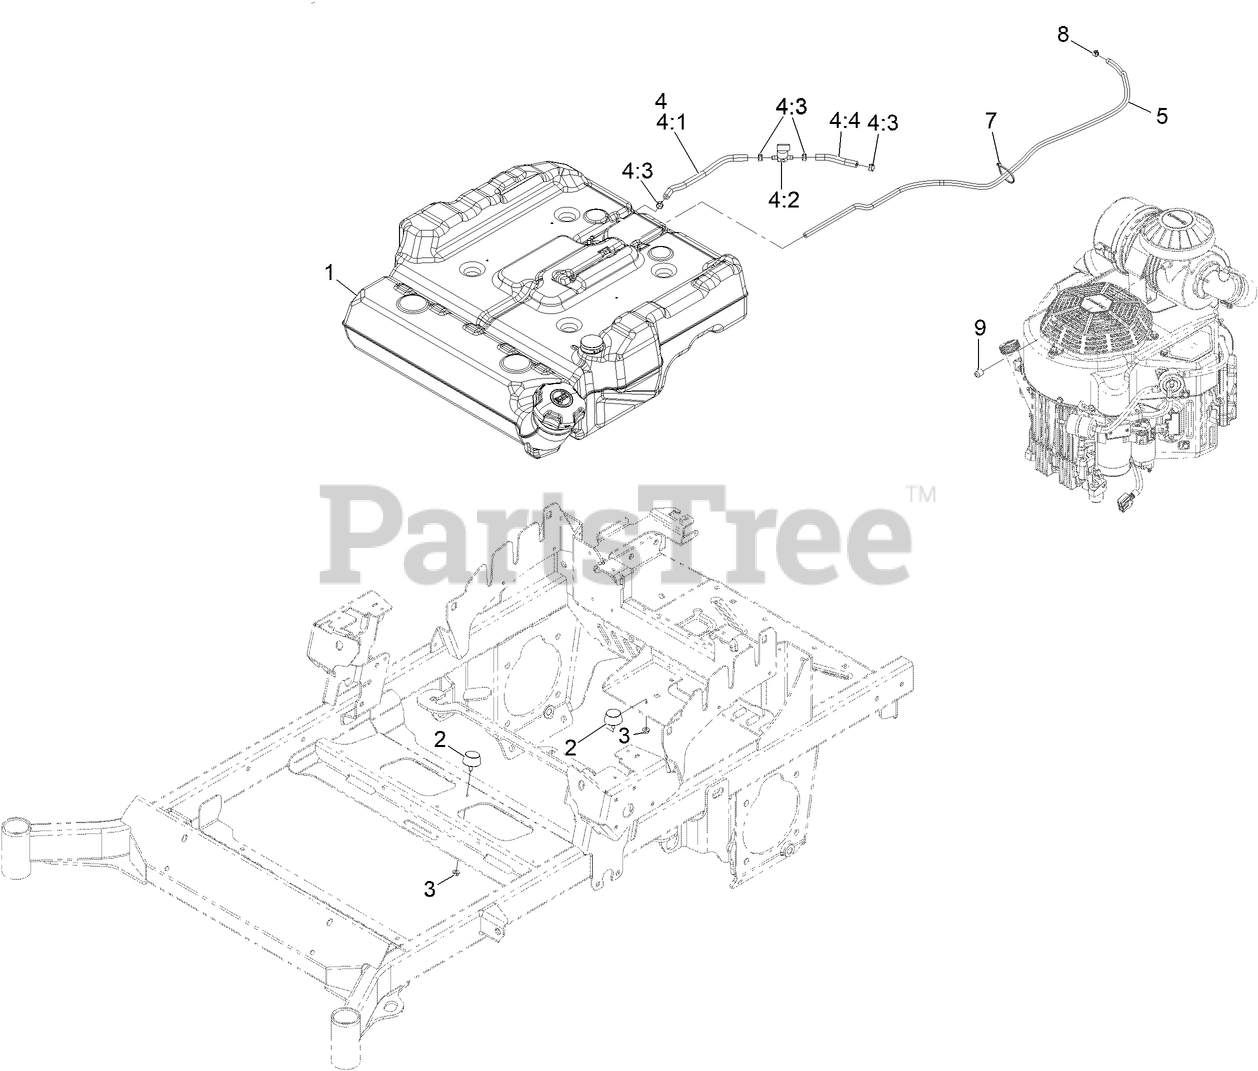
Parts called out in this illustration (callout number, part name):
1	ASM, Fuel Tank
4	ASM, FUEL LINE
4:1	Hose-Fuel
4:2	VALVE-FUEL
4:3	CLAMP-HOSE
4:4	HOSE-FUEL
5	HOSE-FUEL
7	TIE-CABLE
8	CLAMP-HOSE
9	PLUG-PORT
